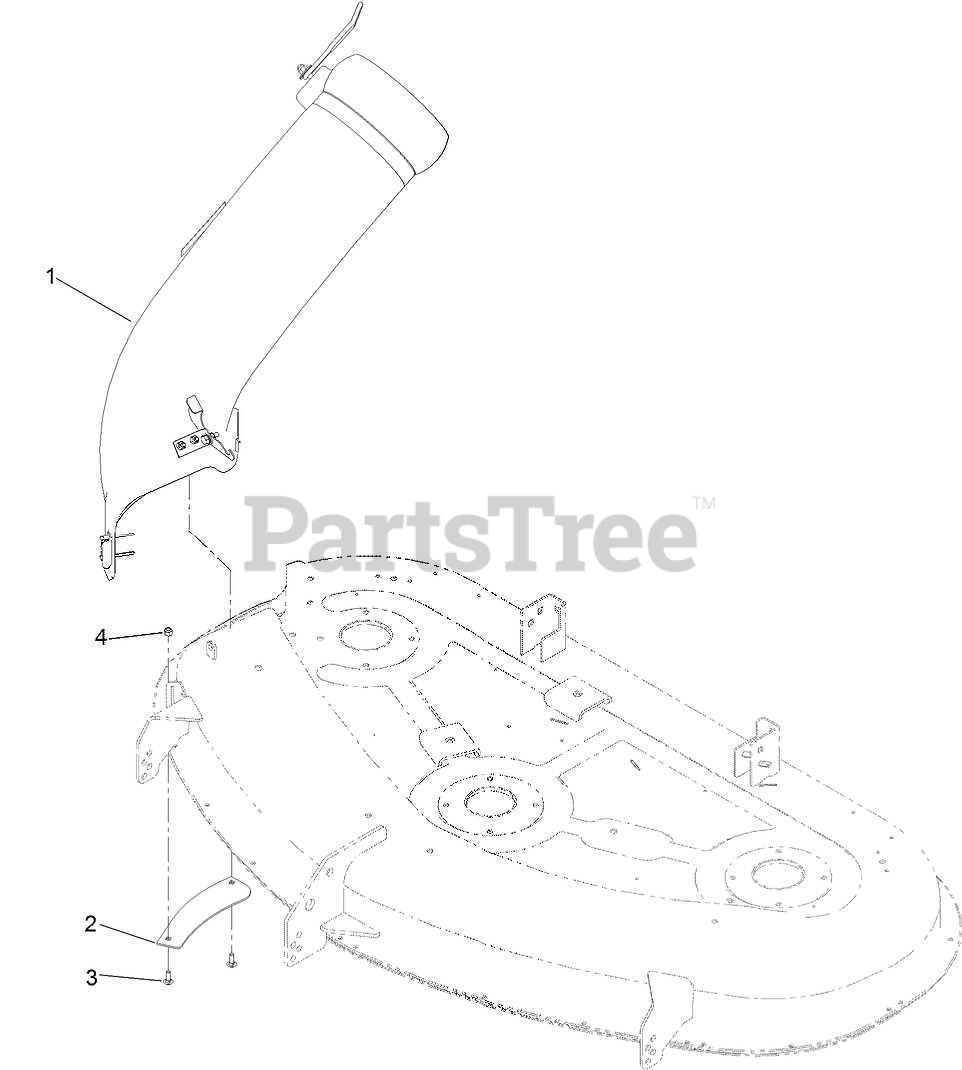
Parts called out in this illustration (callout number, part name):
1	50 INCH CHUTE ASM
2	BAFFLE-BLOWOUT
3	BOLT-CARR
4	NUT-LOCK, NI
